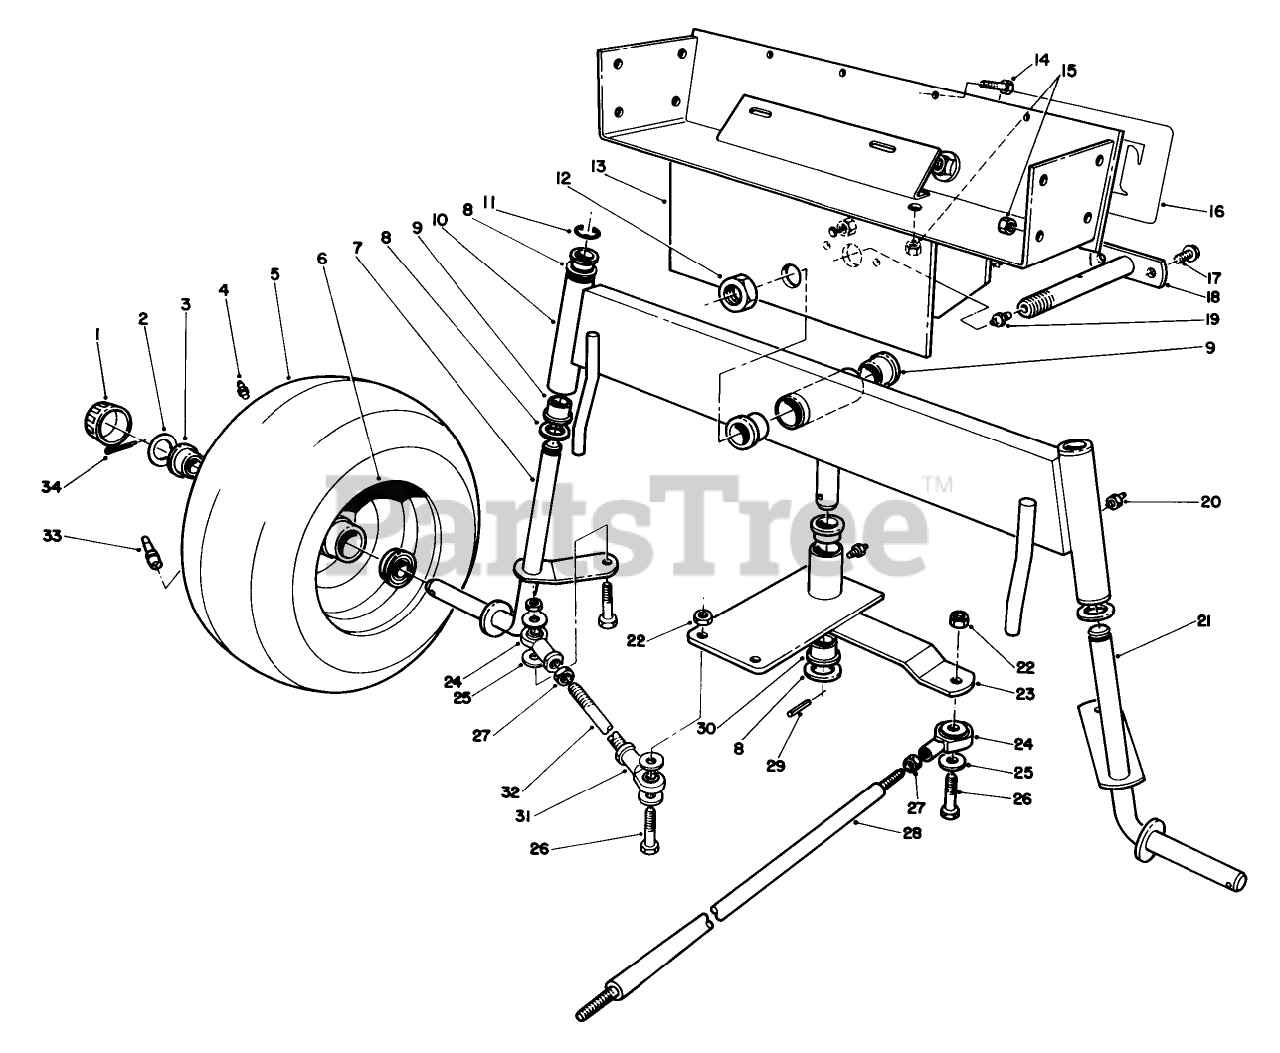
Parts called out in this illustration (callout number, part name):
2	WASHER-PLAIN
4	FITTING-GREASE
8	WASHER-THRUST
9	BUSHING PM
11	E-RING
12	NUT-LOCK NI
14	SCREW-HH
15	NUT-LOCK, NI
17	SCREW-HHFTF
19	FITTING-GREASE
20	GREASE FITTING
22	NUT-HEX
24	BALL JOINT RH
25	WASHER-FLAT
26	SCREW-HH
27	NUT-JAM
29	PIN-SPRING
30	BEARING-FLANGE
31	BALL JOINT LH
32	TIE ROD - STEERING
34	PIN-COTTER
